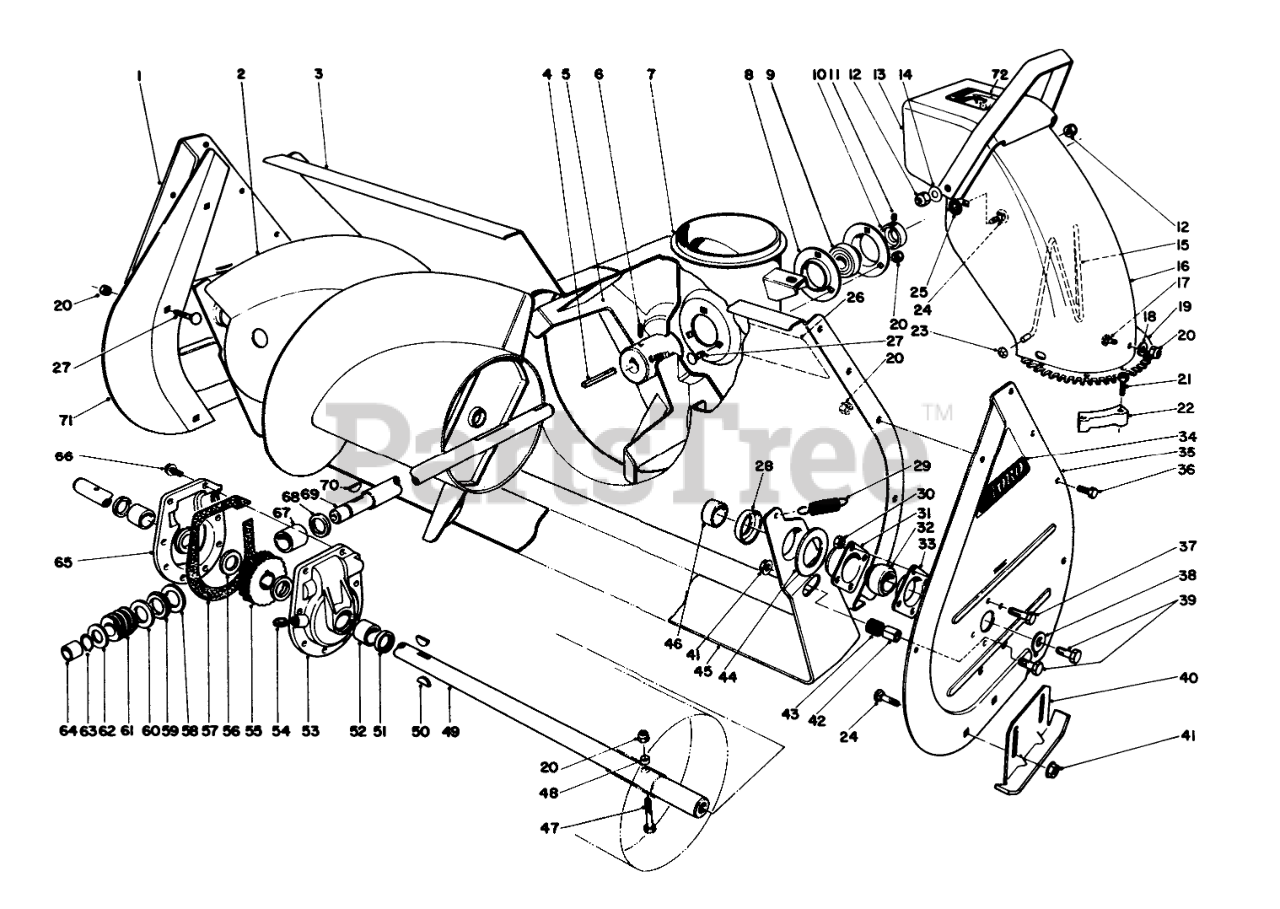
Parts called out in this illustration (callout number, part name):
1	RH AUGER SIDE PLT R
2	RH AUGER ASM - 32"
3	Auger Housing
5	IMPELLER ASM
6	Set Screw
7	CHUTE RING
8	BRG FLANGE
9	Bearing-Impeller (Incl. Ref. 10 & 11)
10	EXT LOCKING COLLAR
11	SCREW-HSH
12	NUT-LOCK, CONE
13	Deflector
14	WASHER-BELLEVILLE
15	WIRE-CHUTE
16	Upper Chute
17	SCREW-CARR
18	WASHER-PLAIN
19	Screw
20	NUT-LOCK, NI
21	SCREW-SPECIAL
22	RETAINER-CHUTE
23	NUT-PUSH
24	SCREW-CARR
25	WASHER-RUBBER
26	Decal-Warning
27	BOLT-CARR
28	Positioner-Scraper
29	SPRING-TENSION
30	NUT-LOCK, CONE
31	BEARING-FLANGE, FRONT
32	BEARING
33	BEARING-FLANGE, REAR
34	AUGER SIDE PLT DECAL
35	LH AUGER SIDE PLT R
36	SCREW-HH
37	SCREW-HH
38	WASHER
39	SCREW-HH
40	AUGER SKID WA R
41	NUT-HF
42	SCRAPER STOP SPACER
43	SCRAPER STOP CUSHION
44	SCRAPER BLADE SPACER
45	SCRAPER BLADE 32" R
46	AUGER SPACER
47	Auger Bolt
48	SPACER-HUB, AUGER
49	32 AUGER SHAFT
50	KEY-WOODRUFF
51	SEAL-OIL
52	BUSHING
53	Gear Case Bushing Assy.-L.H. (Incl. Ref. #51, 52)
54	PLUG-PIPE, SQH
55	GEAR-WORM, 27T
56	WASHER-THRUST
57	GASKET-CASE, GEAR
58	WASHER-THRUST
59	BEARING-THRUST
60	THRUST-WASHER
62	WASHER-THRUST
63	Ring-Snap
64	BUSHING
65	Gear Case Bushing Assy.-R.H. (Incl. Ref. #51, 52)
66	SCREW-TAPTITE
67	BUSHING-SPECIAL
68	RING-QUAD
69	SHAFT-IMPELLER
70	KEY-WOODRUFF
71	Auger Housing Extension R.H.
72	Decal-Danger
